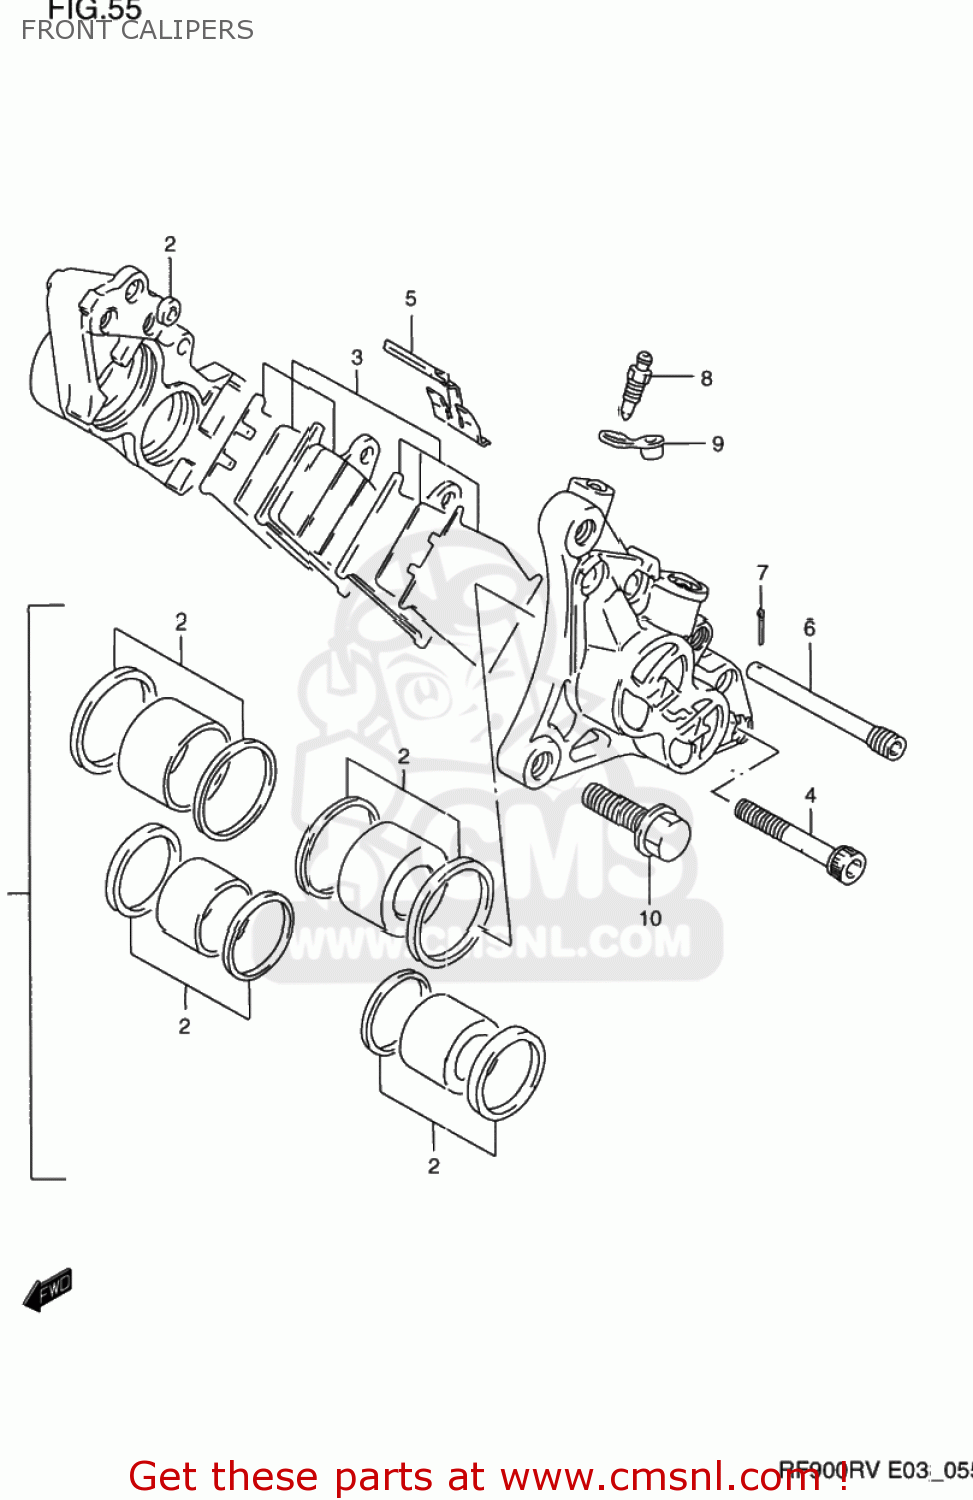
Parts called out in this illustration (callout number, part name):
1	PISTON SET
2	SEAL SET,PISTON
3	PAD & SHIM SET (NAS)
4	BOLT
5	SPRING
6	PIN,HANGER
7	PIN 16X20
8	BLEEDER
9	CAP,BLEEDER
10	BOLT
